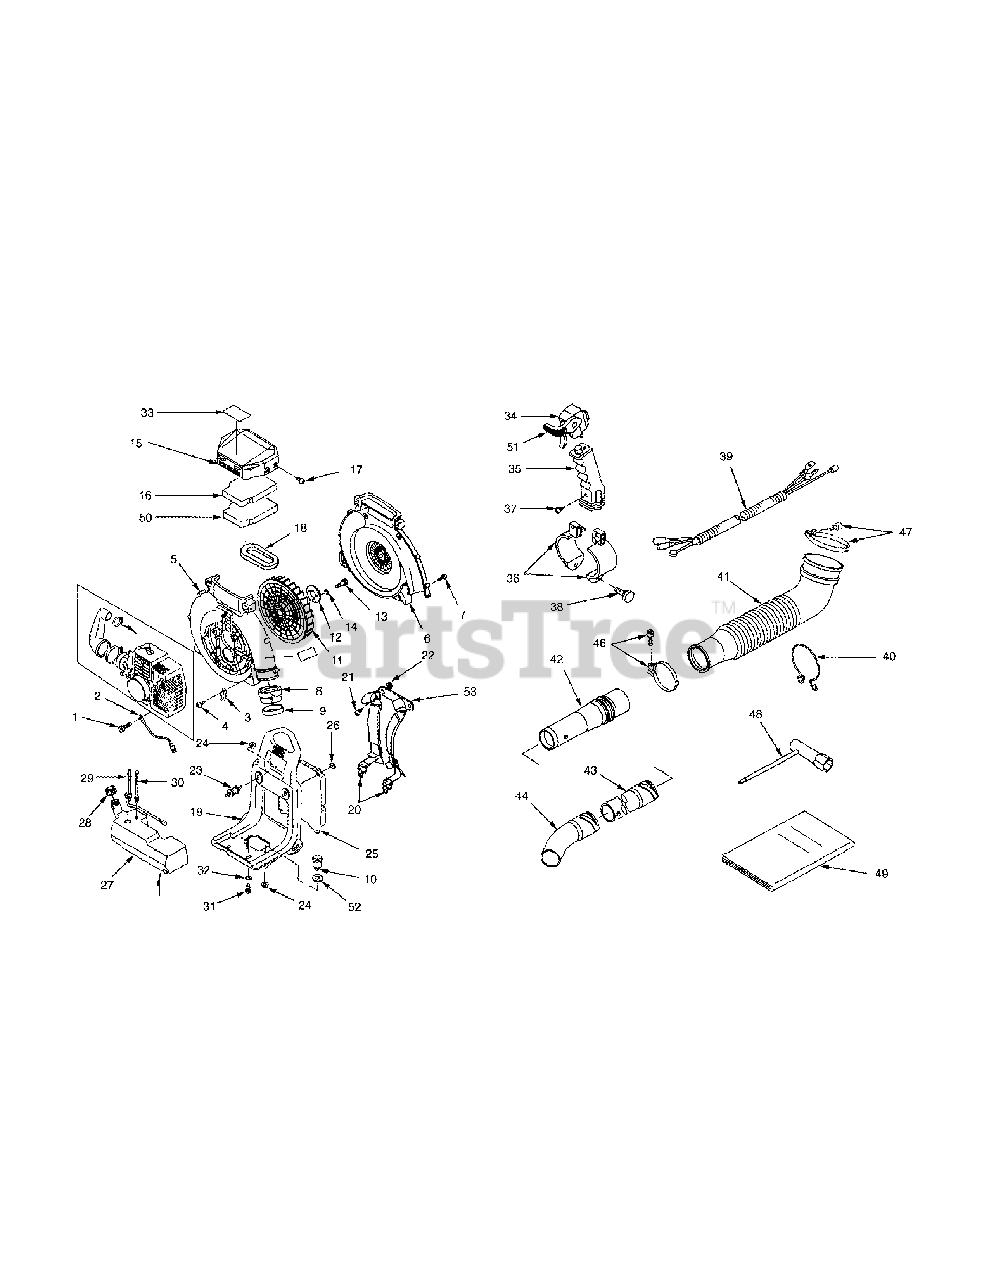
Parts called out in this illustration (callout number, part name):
2	Harness, Wire
14	Washer, Spring
15	Silencer Assembly
16	Element "A", Air Filter
21	Screw, M6x16
28	Cap Assembly, Fuel Tank
29	Filter, Assembly, Fuel
30	Valve Assembly, Reversing
31	Screw, M5x14
33	Name Plate
34	Lever, Throttle
36	Band Assembly
39	Wire Complete, Throttle
41	Pipe, Flexible
42	Pipe, Straight
43	Pipe, Straight
46	Band Assembly
47	Band Assembly
48	Wrench, Spanner Box 19
49	Manual, Operator's
50	Element "B", Air Filter
